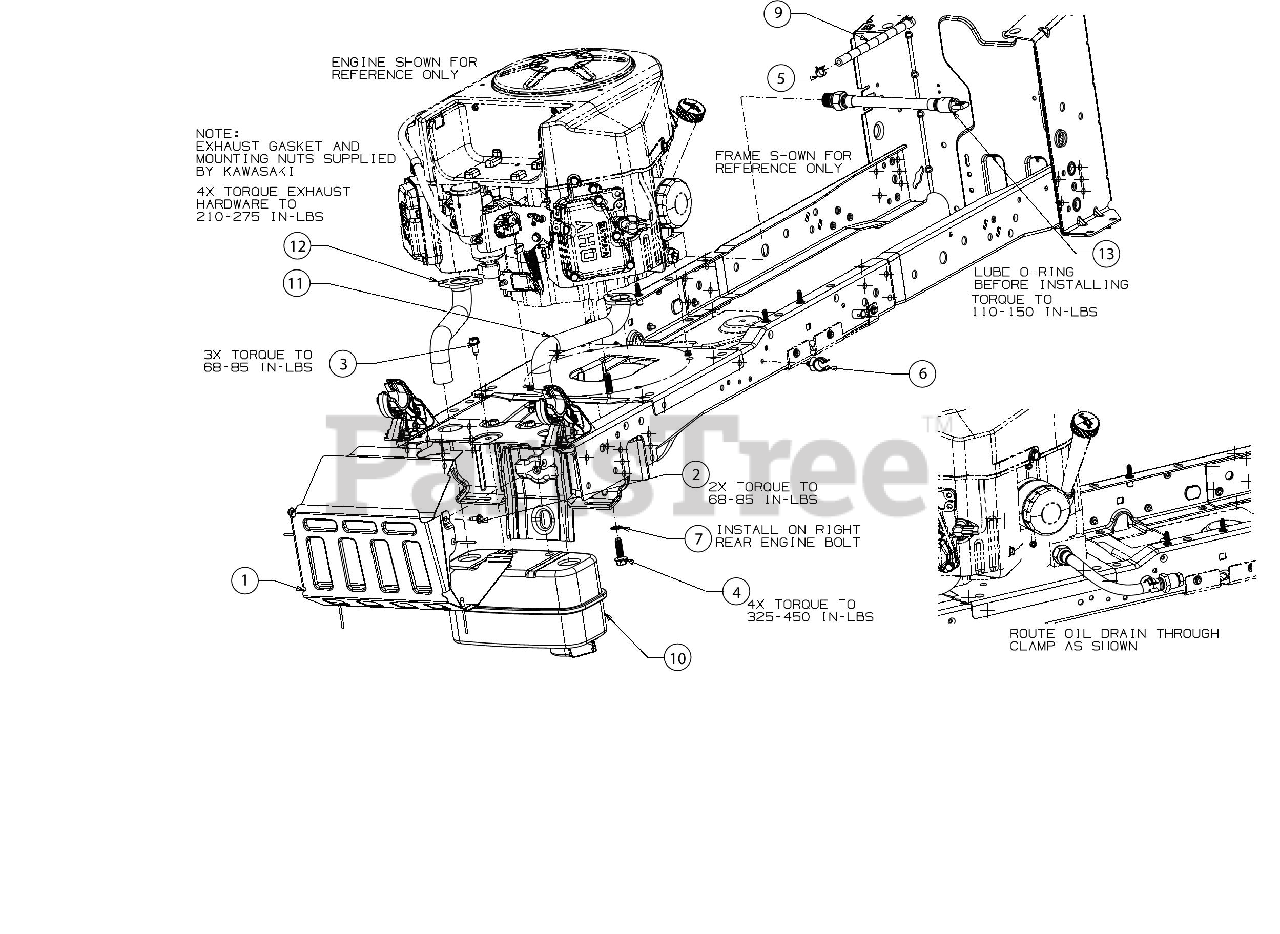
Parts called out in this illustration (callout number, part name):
1	MUFFLER SHIELD ASSEMBLY
2	SCREW M6-1 x .625
3	SCREW M8-1.25 x .750
4	SCREW 3/8-16 X1.250
5	HOSE CLAMP 1/20
6	DRAIN HOSE CLIP
7	LOCK WASHER 3/8
9	FUEL HOSE LOW PERMEATION
10	EXHAUST MUFFLER (TWIN)
11	EXHAUST PIPE (LH) (KAWASAKI)
12	EXHAUST PIPE (RH) (KAWASAKI)
13	OIL DRAIN HOSE M20 THRD
